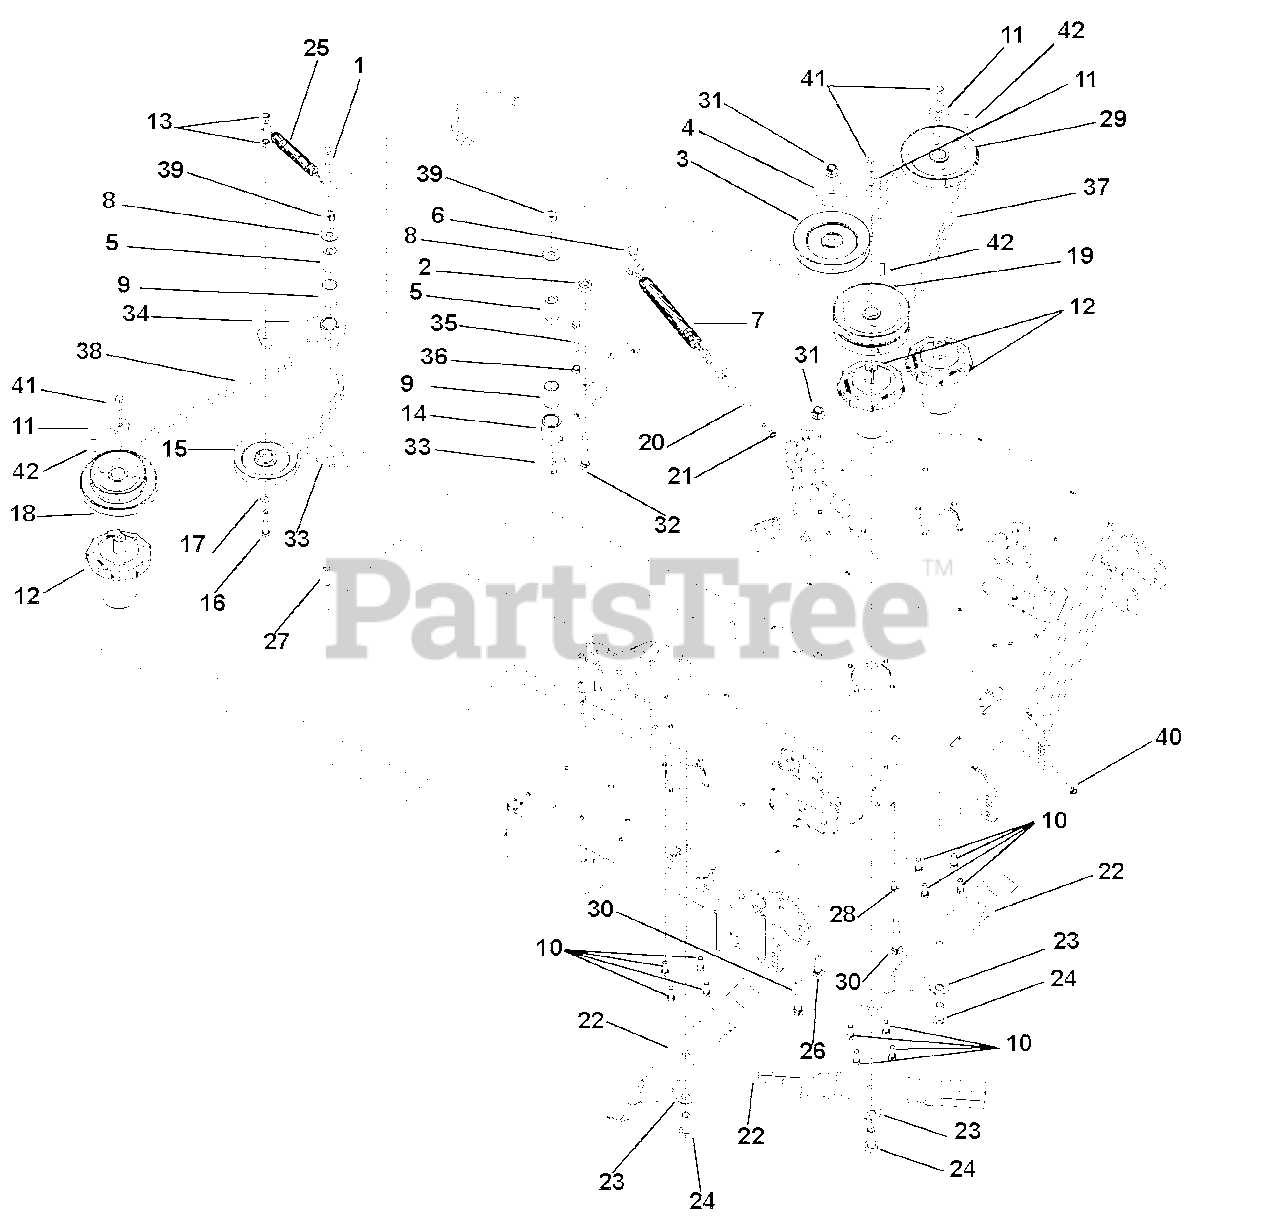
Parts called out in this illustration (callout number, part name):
1	Bolt, Hex .38-16 x 1.50
2	Bushing, Spacer .502 x .997 x .50
3	Sheave, .50" ID x 6.00" OD V-Idler
4	Cap, Idler Bearing Sealing
5	Bushing, Spacer .505/.500 x .999/.996 x 2.05/2.03
6	Bolt, Shoulder EP .38-16 x .30 Hex
7	Spring, Extension (Deck Idler)
8	Washer, Flat Steel .563 x 1.38 x .109
9	Bushing, 1.00 x 1.125 x 1.936
10	Bolt, Hex .38-16 x 1.00
11	Retainer, Sheave
12	Spindle Assembly
13	Nut, Locking Center .38-16
14	Weldment, Idler Arm
15	Idler, V-5.00"
16	Bolt, Hex .38-16 x 2.25
17	Washer, Flat Steel .406 x .812 x .065
18	Pulley, Double, 1" ID x 5.75" & 4.25" OD (991079, 095, 102)
19	Pulley, Double, 1" ID x 5.75" OD (991079, 095, 102)
20	Bolt, .38-16 x 5.50 .62 Diameter Eye
21	Nut, Hex, Jam .375-16
22	Blade, 16.19" Mower (991079, 095, 102)
23	Washer, Bellville .63 x 1.625 x .14
24	Bolt, Hex .62-18 x 1.75 Grade 8 (Torque to 115 – 125 ft. lbs., 155 – 169 N-m)
25	Spring, Extension
26	Bolt, Round Head Square Neck .50-13 x 1.5, Full Thread
27	Nut, Coupling .375-16 x 1.75
28	Bolt, Round Head Square Neck .38-16 x 1.00
29	Pulley, V, 1" ID x 5.75" OD (991079, 095, 102)
30	Bolt, Round Head Square Neck .50-13 x 3.25 G5YZ
31	Nut, .50-13 Nyloc Flange
32	Bolt, Round Head Square Neck .50-13 x 3.00
33	Washer, Flat .640 x 1.75 x .250
34	Weldment, Idler Arm
35	Bolt, Hex .38-16 x 2.75
36	Nut, Hex .38-16
37	Belt, BB 118.00 Wrapped Hex (991079, 095, 102)
38	Belt, B 51.18 Raw Cogged (991079, 095, 102)
39	Nut, Locking Center .50-13
40	Nut, Lock Center Jam .375-16
41	Bolt, Hex .38-16 x 2.75 Grade 8
42	Key, Square .25 x .25 x 1.00
